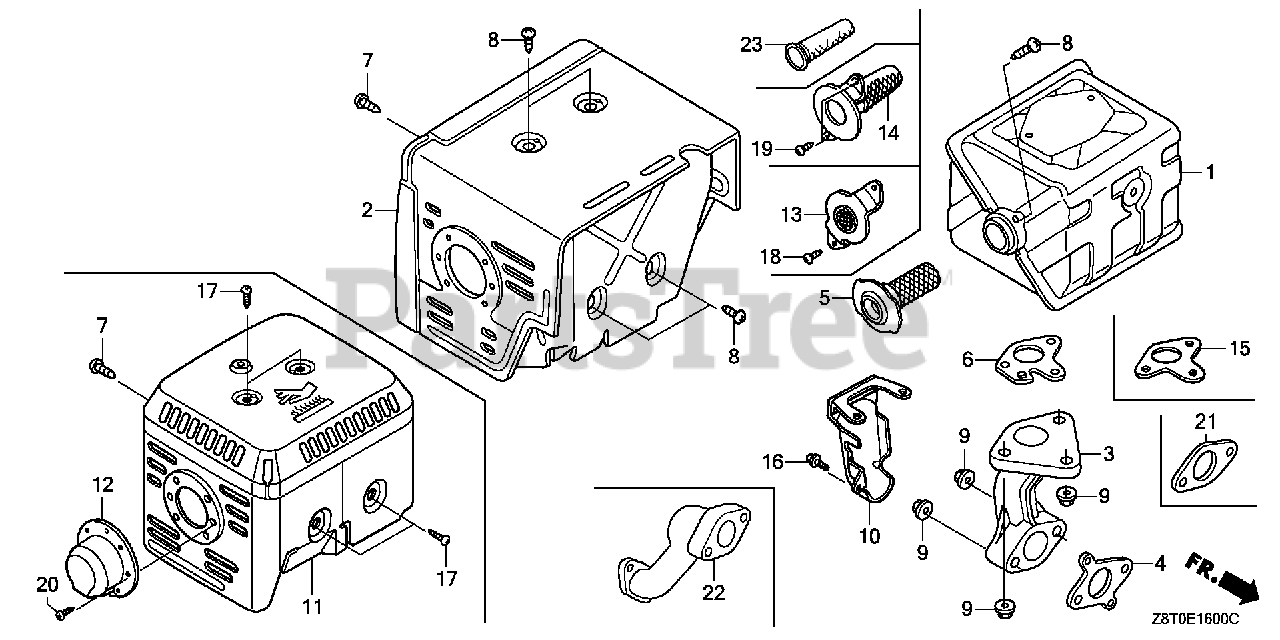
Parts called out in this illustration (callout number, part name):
1	MUFFLER
3	PIPE, EX.
4	GASKET, EX. PIPE
6	GASKET, MUFFLER (ARRESTER)
6	GASKET, MUFFLER (ARRESTER)(THAI LEAKLESS)
7	SCREW, TAPPING (6X10)
9	NUT, FLANGE (8MM)
11	PROTECTOR, MUFFLER
14	ARRESTER, SPARK
17	SCREW, TAPPING (5X8)
19	SCREW, TAPPING (5X8)
